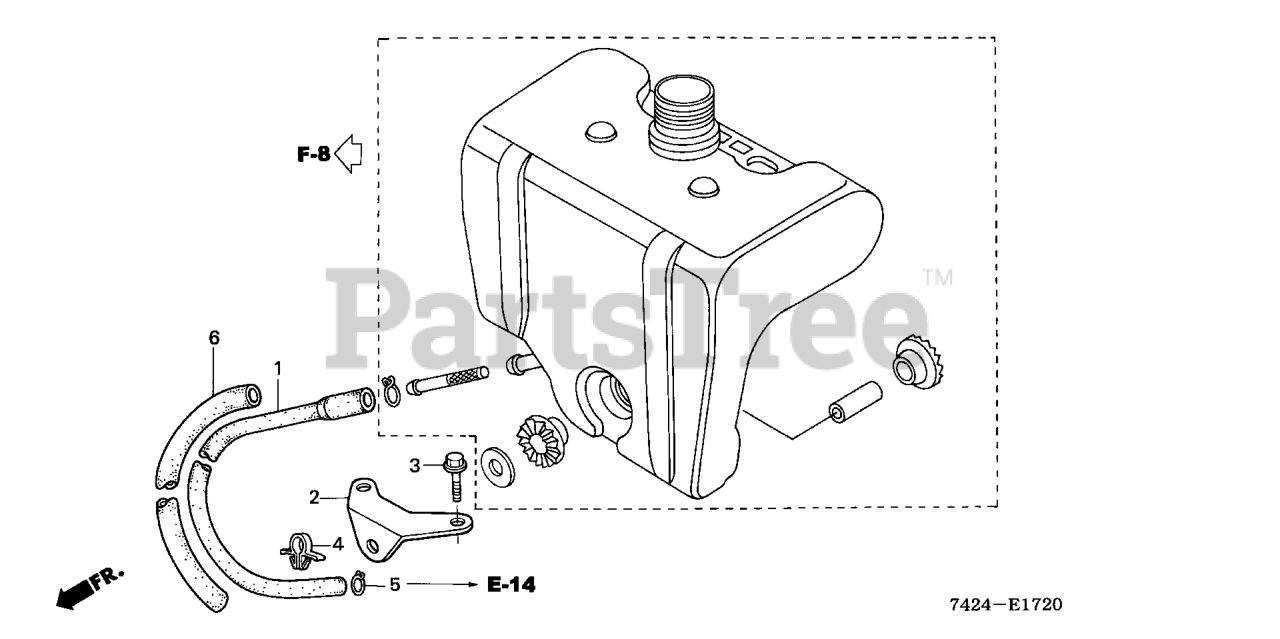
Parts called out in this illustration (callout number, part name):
1	TUBE, FUEL
2	STAY, TANK
3	BOLT, FLANGE (6X14)
4	CLIP, WIRE HARNESS
5	CLIP, TUBE (B8)
6	BULK HOSE, VINYL (9X11X3000) (9X11X150)
